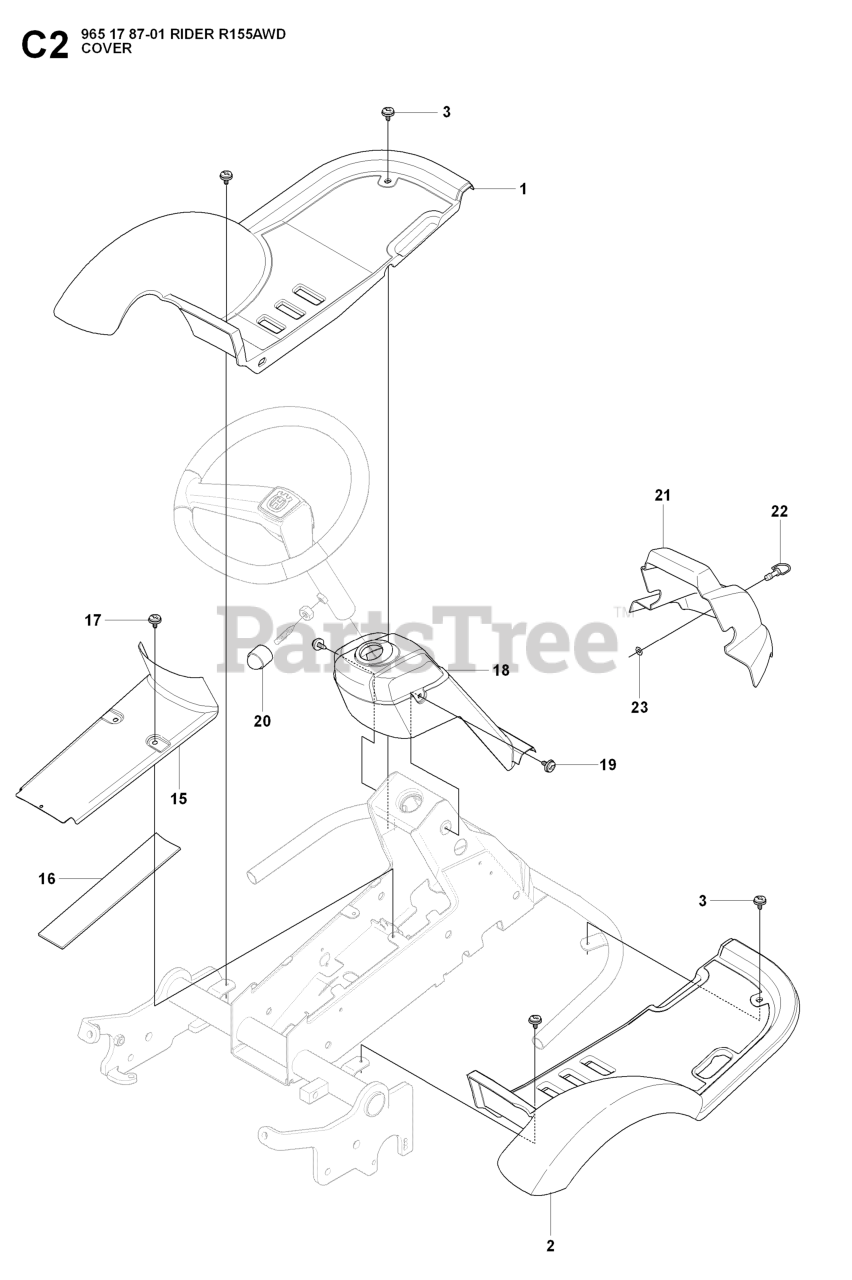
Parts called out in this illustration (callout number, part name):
1	FOOT PLATE
2	FOOT PLATE
20	PROTECTIVE COVER
22	BOLT
